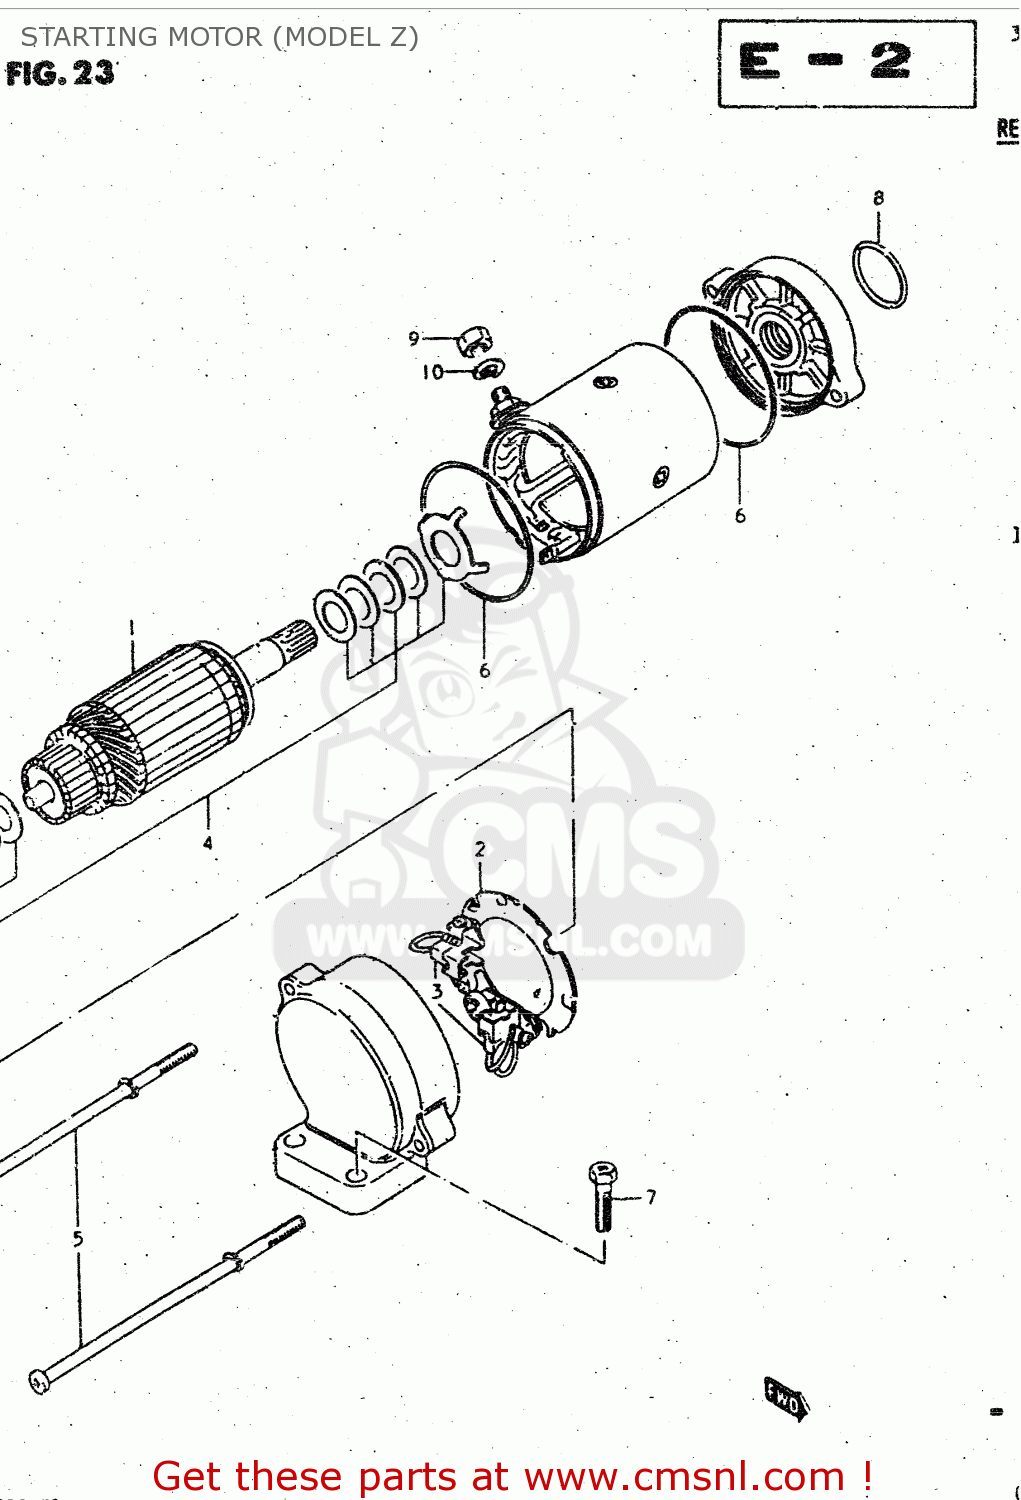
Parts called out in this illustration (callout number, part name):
1	ARMATURE
2	HOLDER ASSY
3	BRUSH SET
4	SHIM SET
5	BOLT,STARTING MOTOR HOUSING
6	O RING
7	SCREW (6X25)
8	O RING(D:2,ID:24.5)
9	NUT 6MM
10	LOCK WASHER
